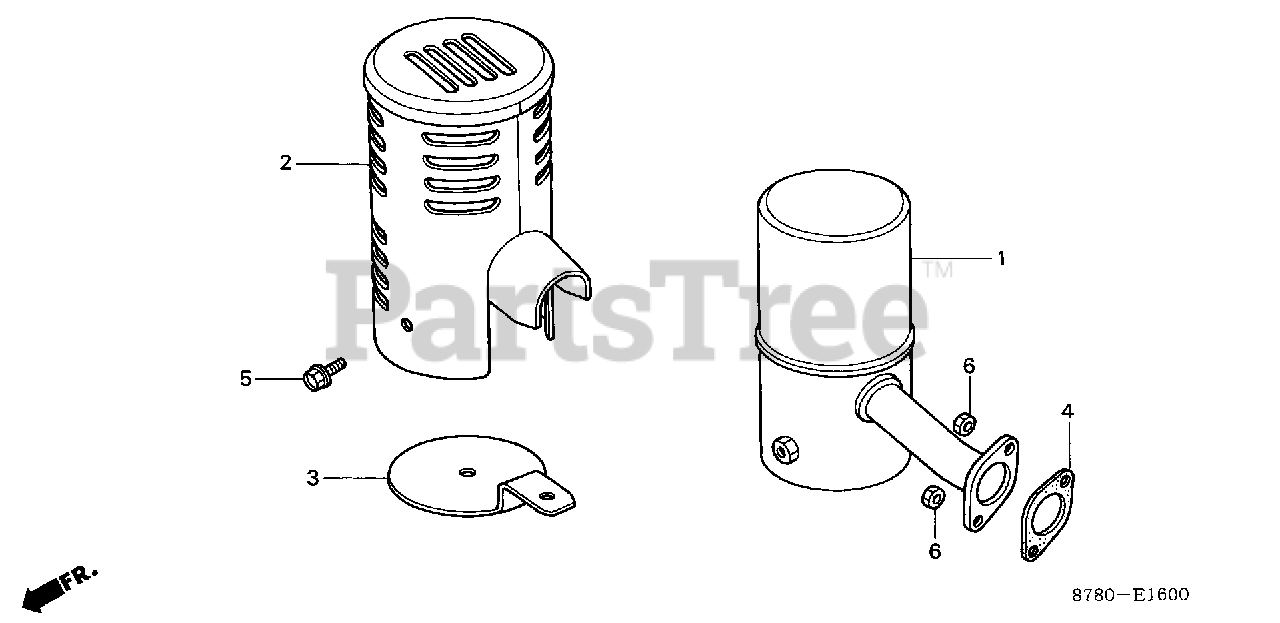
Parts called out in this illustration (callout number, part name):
1	MUFFLER (NOT AVAILABLE)
2	PROTECTOR, MUFFLER (NOT AVAILABLE)
3	PLATE, MUFFLER (LOWER) (NOT AVAILABLE)
4	GASKET, MUFFLER (NOT AVAILABLE)
5	BOLT, HEX. (6X6)
6	NUT, HEX. (6MM)
